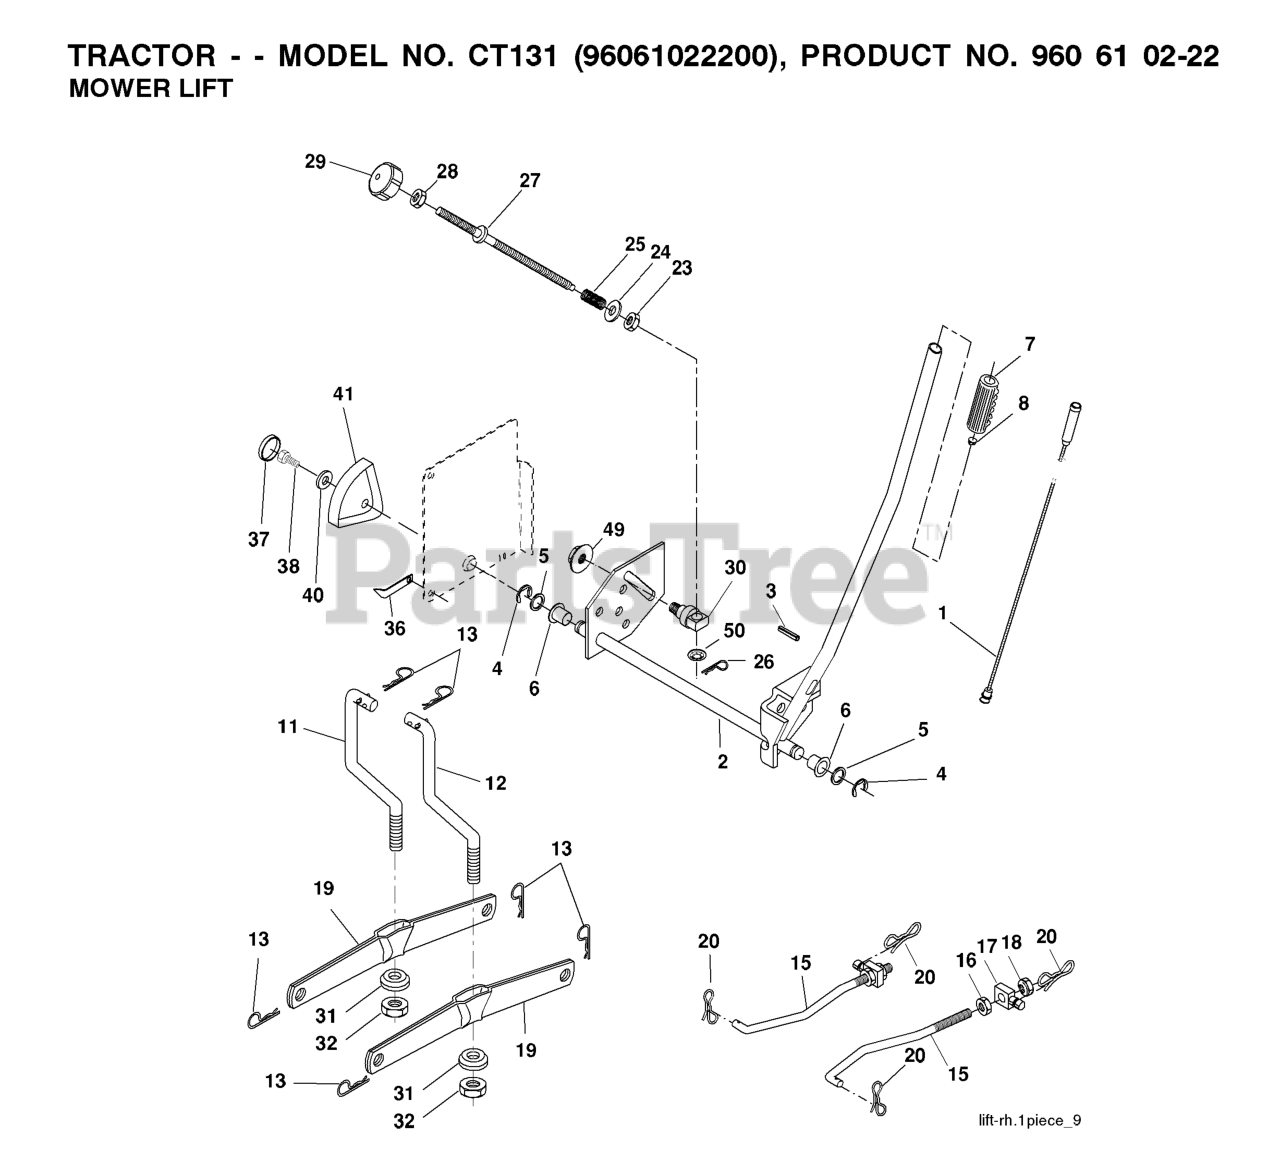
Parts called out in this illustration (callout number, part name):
1	WIRE ASM INNER W/ PLUNGER LT
2	SHAFT ASM R HANDLE
3	PIN GROOVE.
4	RETAINING RING LT
6	BEARING.NYLON
8	PLUNGER BUT KIT
11	LINK
12	LINK
13	RETAINER-SPRNG RB
15	LINK.SUSPENSION.FRONT
16	NUT.HEX.JAM.1/2-13
18	NUT.LK.W/WSH.1/2.
19	ARM.REAR.SUSPENSION
20	PIN.COTTER.7/16.BOW TI.
25	SPRING**
26	RETAINER CLIP
27	ROD ADJ LIFT
28	NUT
29	KNOB INF 3/8-16
31	BEARING.PIVOT.LIFT
32	NUT CROWNLOCK 3/8-24
36	POINTER, HEIGHT INDICATOR(2 2)
38	SCREW 5/16-18X1
41	HEIGHT INDICATOR
49	NUT
50	NUT PUSH M
